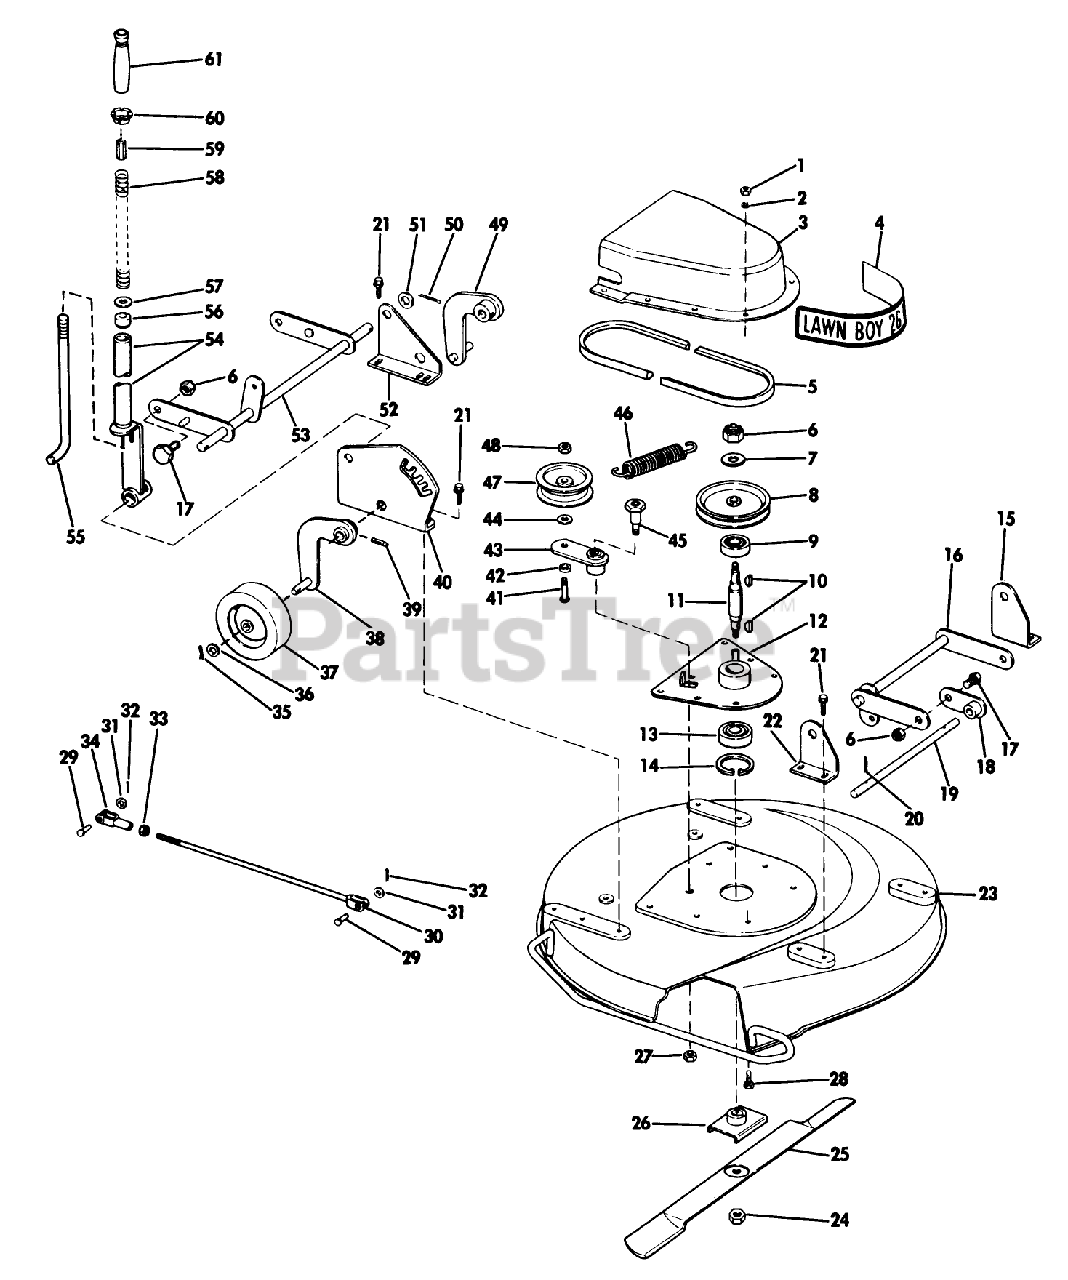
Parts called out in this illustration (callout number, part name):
1	Nut-Hex
4	Decal-LAWN-BOY BELT COVER
19	Rod, Mower Pan Support
20	Cotter Pin
33	Jam Nut-Stabilizer Link Assembly
48	LOCKNUT
59	Button-Release
